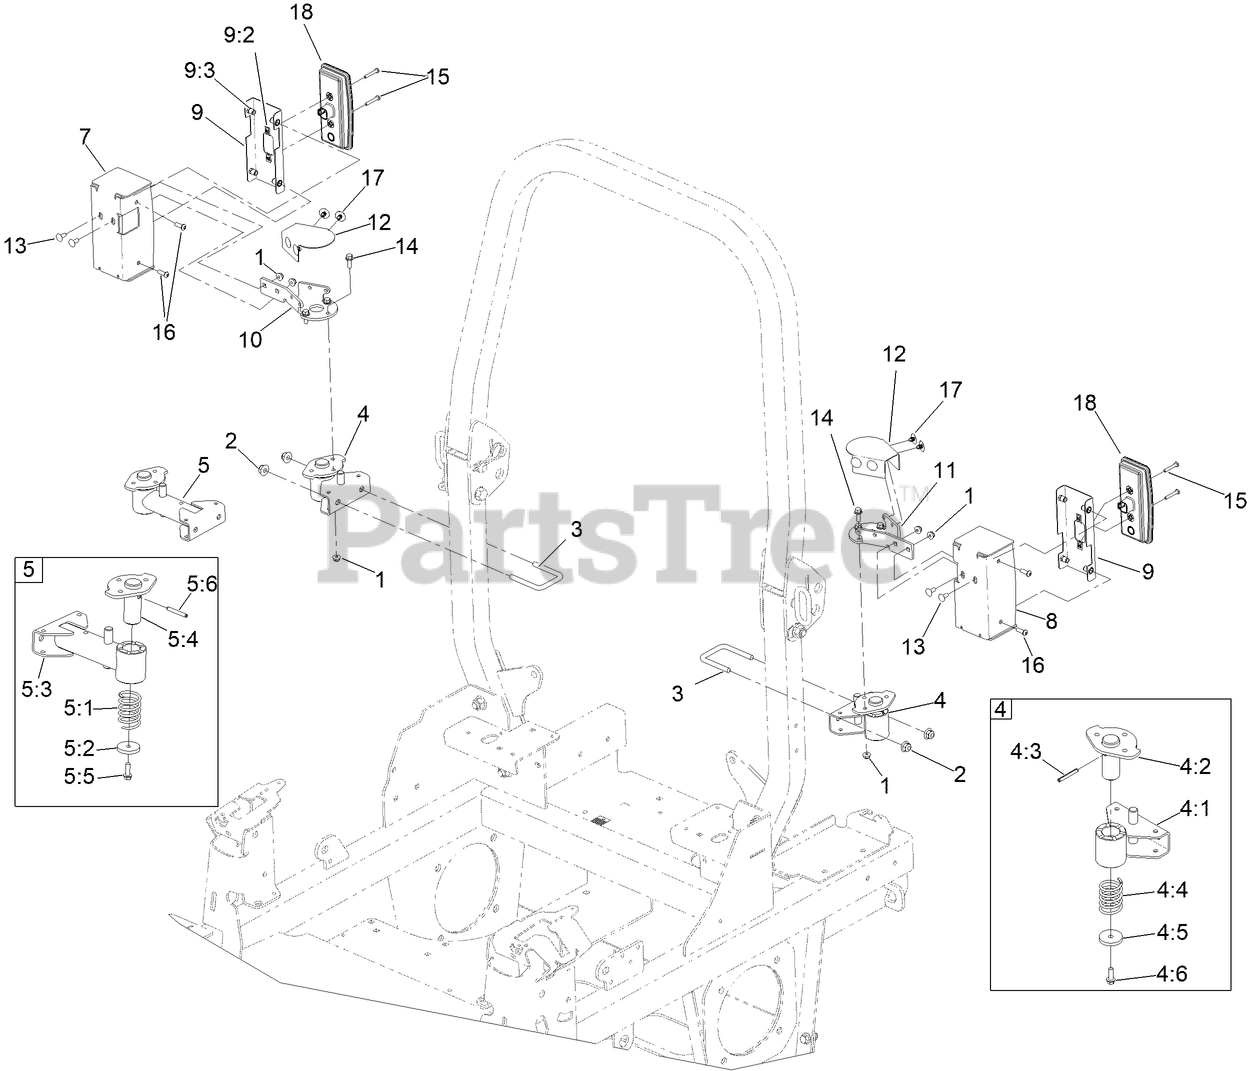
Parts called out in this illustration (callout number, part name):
1	NUT-HF
2	NUT-HF, NI
3	BOLT-U
4	BRACKET-PIVOT, ASM
4:1	PIVOT BRACKET ASM [BLACK]
4:3	PIN-ROLL
4:4	SPRING-COMPRESSION
4:5	WASHER 34 DIA X 7 DIA X 5 THK
4:6	SCREW-HWH
5	BRACKET-PIVOT, ASM WIDE
5:1	SPRING-COMPRESSION
5:2	WASHER 34 DIA X 7 DIA X 5 THK
5:3	PIVOT BRACKET [BLA
5:5	SCREW-HWH
5:6	PIN-ROLL
7	HOUSING-LIGHT, RH
8	HOUSING-LIGHT, LH
9	INNER MOUNT ASM
9:2	NUT-SPEED
9:3	NUT-CLINCH, HEX
10	MOUNT-LIGHT, RH
11	MOUNT-LIGHT, LH
12	COVER-MOUNT
13	SCREW-CARR
14	SCREW-HHF
15	SCREW-PPH
16	SCREW-HSBH
17	RIVET-PLASTIC
18	LIGHT-REAR TAIL/STOP/TURN
